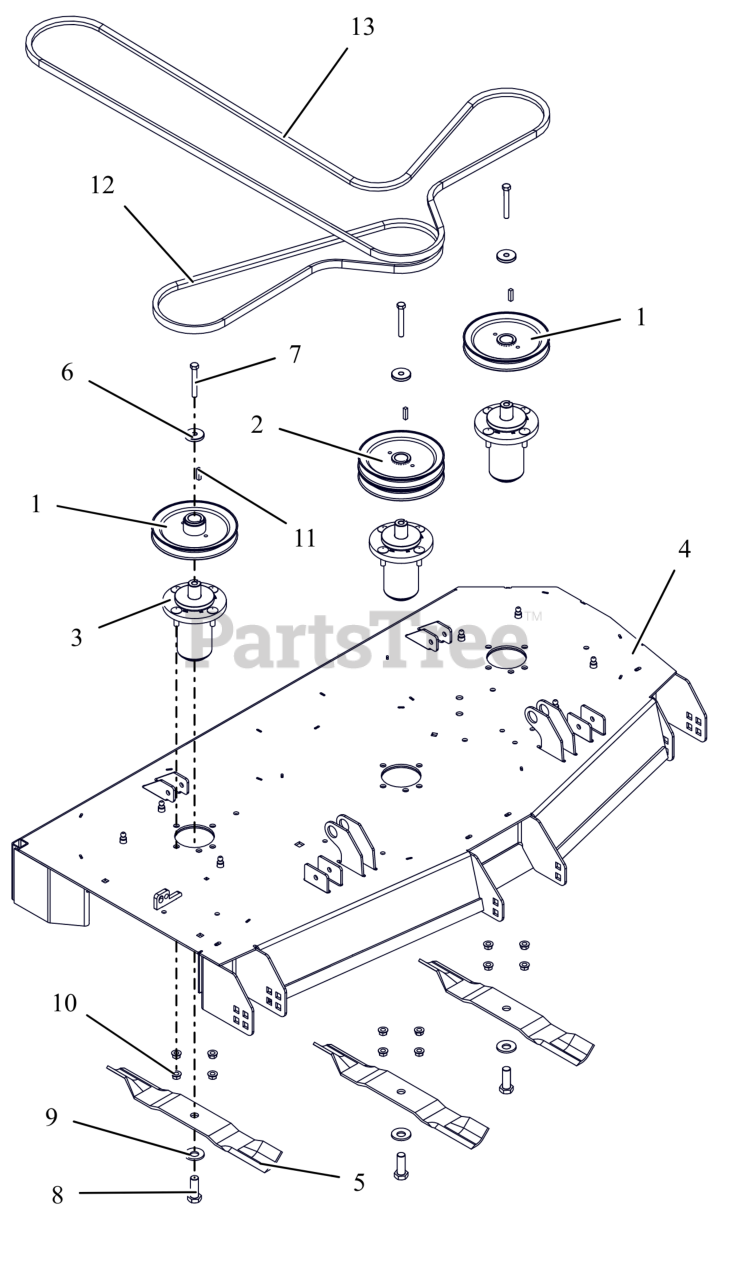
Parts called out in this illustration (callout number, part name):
1	PULLEY, V-1" ID X 6.75" OD
2	PULLEY, DOUBLE-1"ID X 6.75"OD
3	ASM, MAINT FREE ALUM SPINDLE
4	KIT, DECK-52 W/DECALS 7GA XF3 RED
5	BLADE, 18"
6	RETAINER, SHEAVE
7	BLT, HEX .38-16X2.75 G8 ZCC
8	BLT, HEX .62-18X1.75 G8 ZCC
9	WSHR-BLVL .669X1.535X.138
10	NUT-LK-CTR-FLG .375-16 GF ZCC
11	KEY, SQ .25X.25X1.00 RC 40-50
12	V-BELT, B-COGGED
13	V-BELT, HB SECTION
